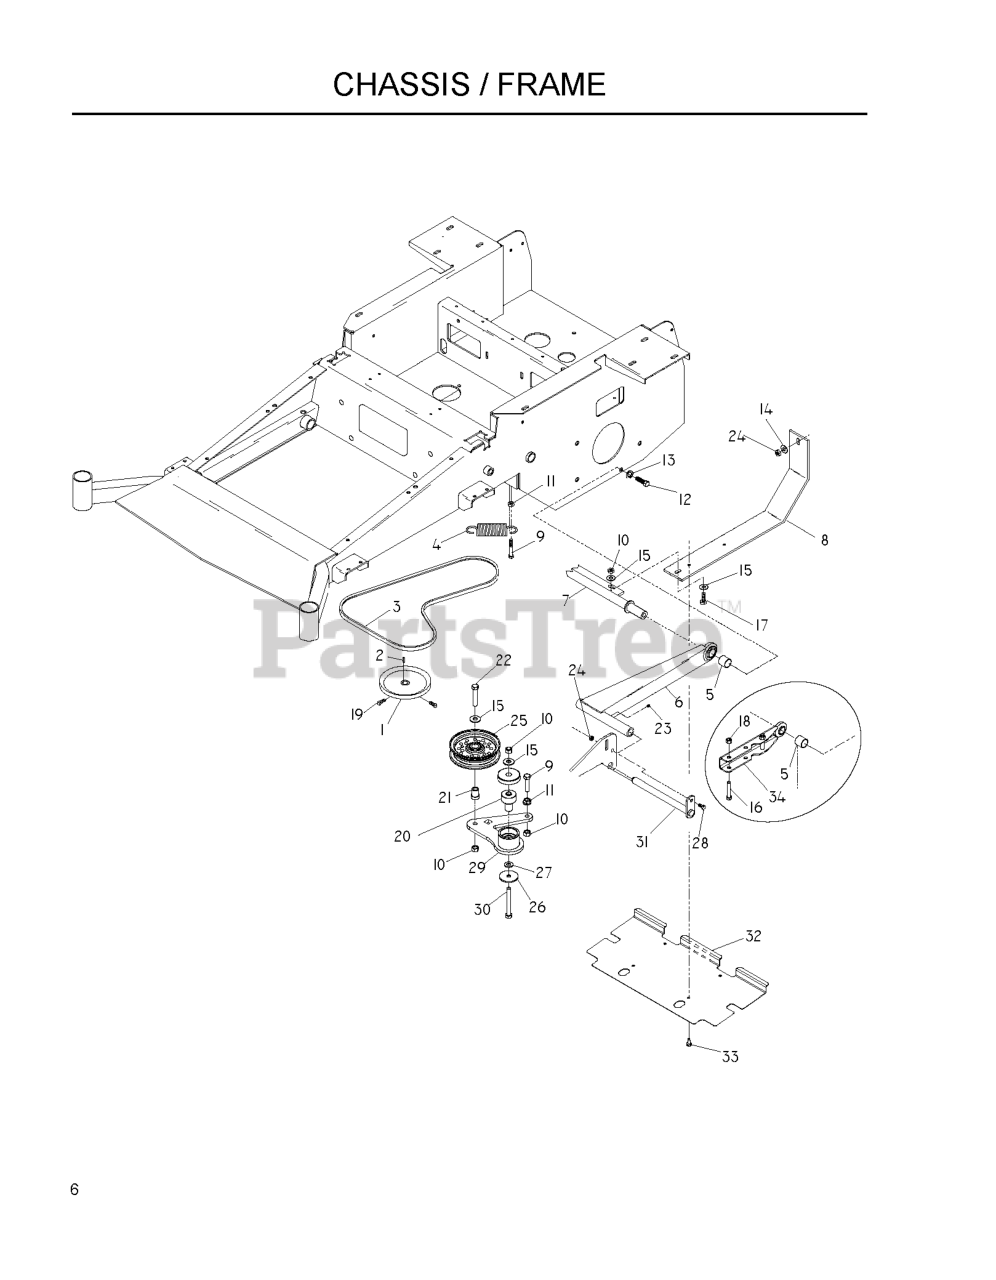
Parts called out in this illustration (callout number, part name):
2	KEY 5 MM SQ X 25 MM
3	PUMP BELT
5	SPACER, STRUT
6	STRUT 72"
6	STRUT
7	CROSS SHAFT, STRUT - BLK
8	SKID PLATE
9	HCS 3/8C X 1 1/2
10	NUT 3/8-16 NYLOC
11	NUT 3/8C WHIZ
12	BLADE BOLT/WASHER
13	WASHER 7/16 LOCK
14	WASHER 5/16 FLAT
15	WASHER 3/8 FLAT
16	HCS 1/2C X 3 1/4
17	HCS 3/8-16X1.GRD.5.ZD
18	NUT 1/2-13 HEX NYLOC ZD
19	SCREW 5/16C X 5/8 SQ HEAD
20	PIVOT, BEARING
21	BUSHING, IDLER FLANGE
22	HCS 3/8C X 2
23	ZERK
24	NUT 5/16 NYLOC
25	IDLER PULLEY
26	WASHER, 3/8 SPEC
27	WASHER 3/8 SAE FLAT
28	HCS 5/16C X 1
29	ARM, IDLER - W/BEARINGS
30	HCS 3/8C X 3
31	PIN WELDMENT
31	PIVOT PIN
32	REAR DEBRIS SHIELD
33	BOLT 3/8-16 X 1.0
34	STRUT WELDMENT, REAR
